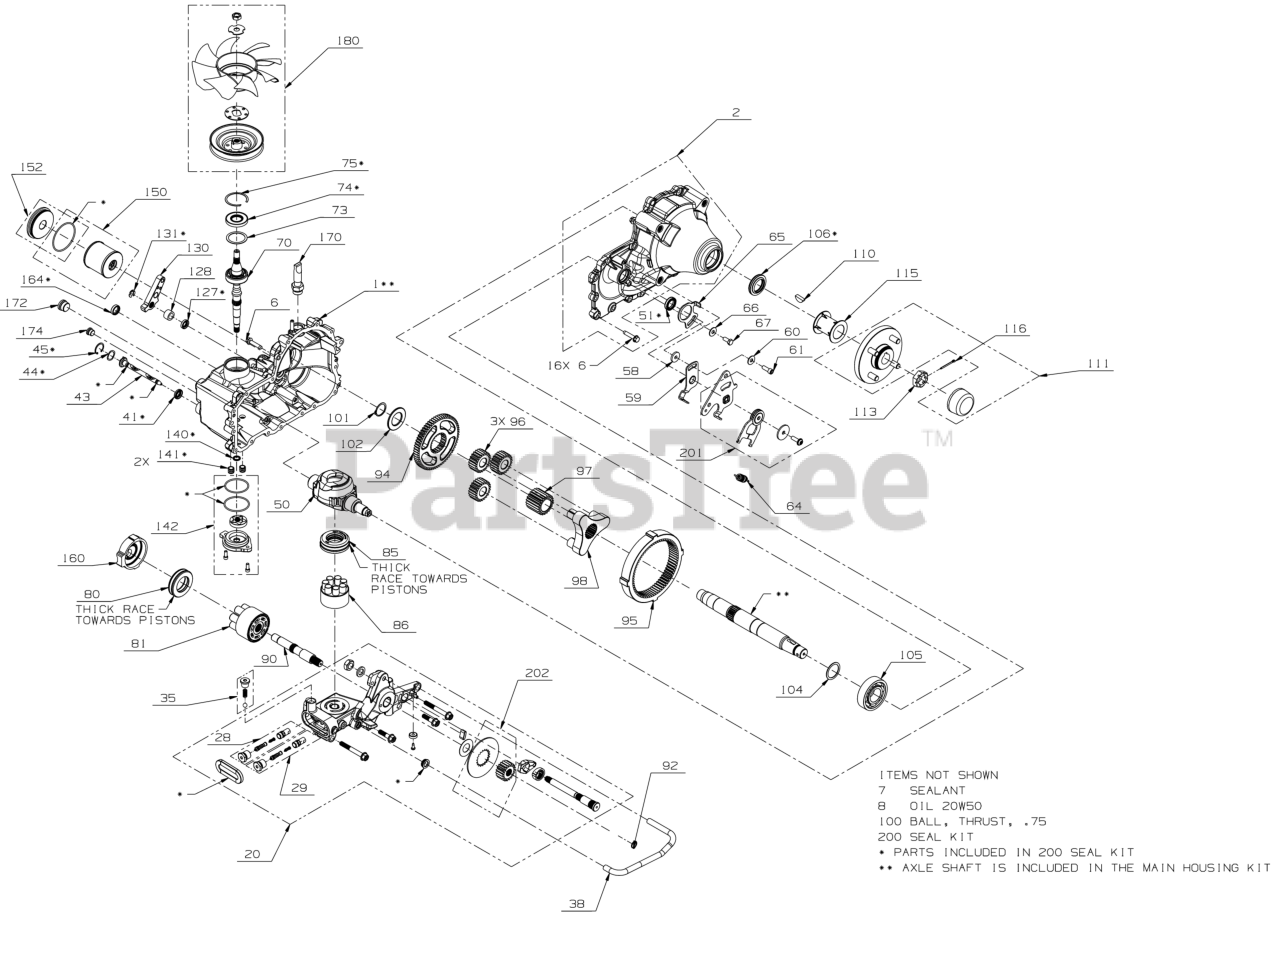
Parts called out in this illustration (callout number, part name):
1	MAIN (LH) KIT
2	SIDE HOUSING (LH) KIT
6	HOUSING SCREW
7	SEALANT-HOUSING
20	CENTER SECTION (LH) KIT
28	SHOCK VALVE KIT
29	SHOCK VALVE KIT
35	CHARGE RELIEF KIT
38	FILTER KIT-LH
41	LIP SEAL 12 X 24 X 5
43	ACTUATOR BYPASS ASM
44	WAVE WASHER 1.00 X .78 X .07
45	RETAINING RING HO-102
50	16CC MACHINED SWASHPLATE
51	LIP SEAL 22 X 32 X 7
58	SPACER .32 x 1.005 x .179
59	ARM-NEUTRAL (LH)
60	FLAT WASHER
61	SCREWS KIT-RTN
64	EXTENSION SPRING
65	STOP PLATE-LH
66	FLAT WASHER
67	SCREW 5/16-18.75 HHCS
70	INPUT SHAFT KIT
73	FLAT WASHER 1.559X1.944X.040
74	LIP SEAL 25 X 52 X 7
75	RETAINING INTERNAL RING
80	PLASTIC THRUST BEARING
81	BLOCK KIT-21CC CYL
85	THRUST BEARING
86	16CC CYLINDER BLOCK KIT
90	MOTOR SHAFT
92	RETAINING RING
94	65T/22T GEAR
95	RING GEAR 68T
101	RETAINING RING
102	AXLE GEAR SPACER
104	FLAT WASHER 1.40 X 1.75 X .05
105	BALL BEARING 35 X 80 X 21
106	LIP SEAL 1.375 X 2.062 X .250
110	WOODRUFF KEY 5/16 X 1
111	4 BOLT HUB KIT
113	SLOTTED 1-20 NUT
115	AXLE TUBE 1.40 X 2.22
116	COTTER PIN 9/64 X 1.5
127	LIP SEAL .562 X .875 X .18
128	SPACER-.57 X .86 X .53
130	ACTUATING HANDLE
131	RETAINING RING
140	LIP SEAL .500 X .688 X .094
141	TUBE-CHARGE TRIPLE O-RING
142	CHARGE COVER KIT
150	FILTER KIT
152	FILTER PLUG KIT
160	MOTOR SWASH PLATE
164	PLUG SEAL .945 X .250
170	STRAIGHT FITTING 7/8 SAE
174	PLUG-STRAIGHT THRE
180	FAN/PULLEY KIT
200	OVERHAUL SEAL KIT
201	RTN BI-DIRECTIONAL KIT
202	BRAKE ROTOR,GEAR KIT
